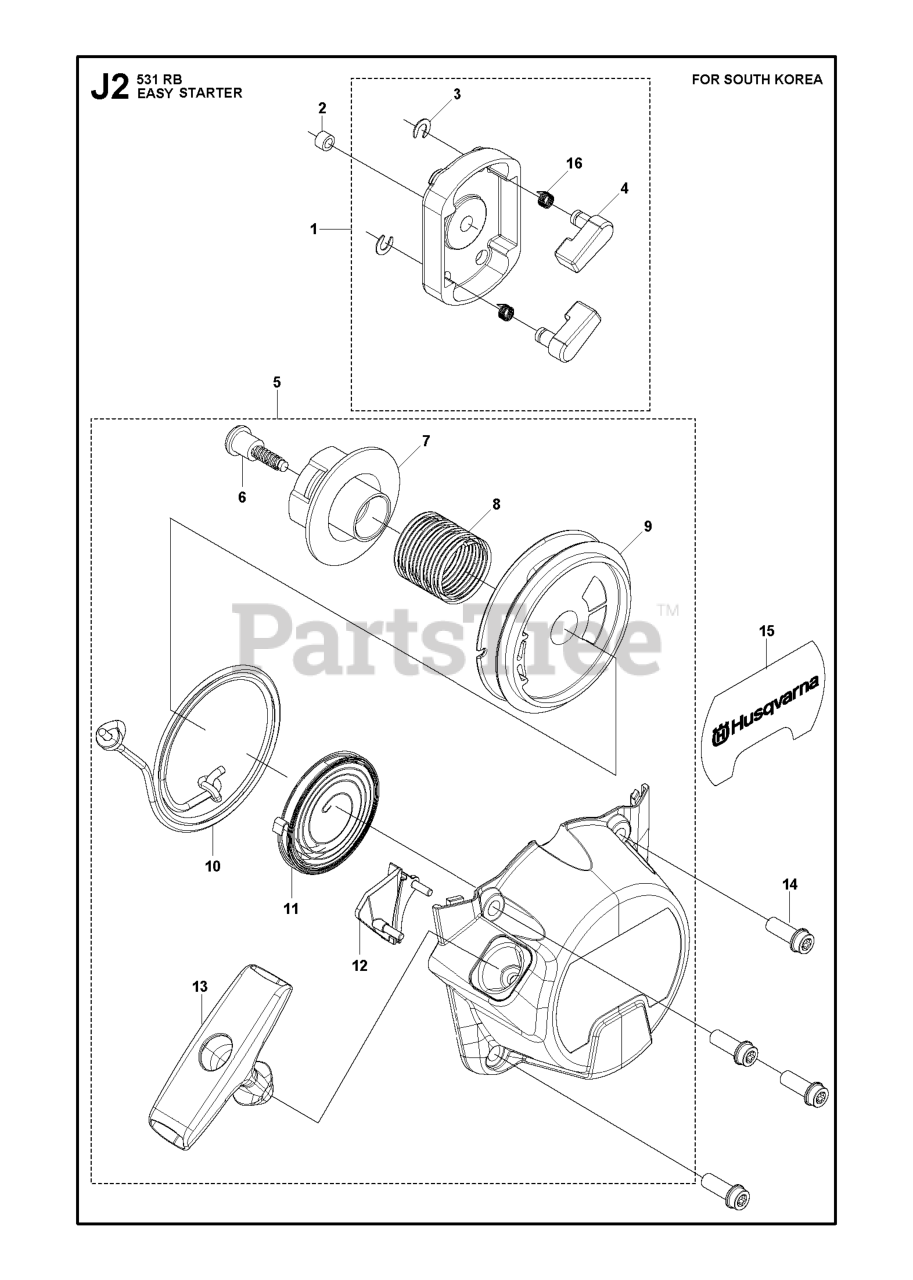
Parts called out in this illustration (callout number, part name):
2	COLLAR
3	E-RING
8	SPRING
9	REEL
10	ROPE
11	SPRING, SPIRAL
13	HANDLE
